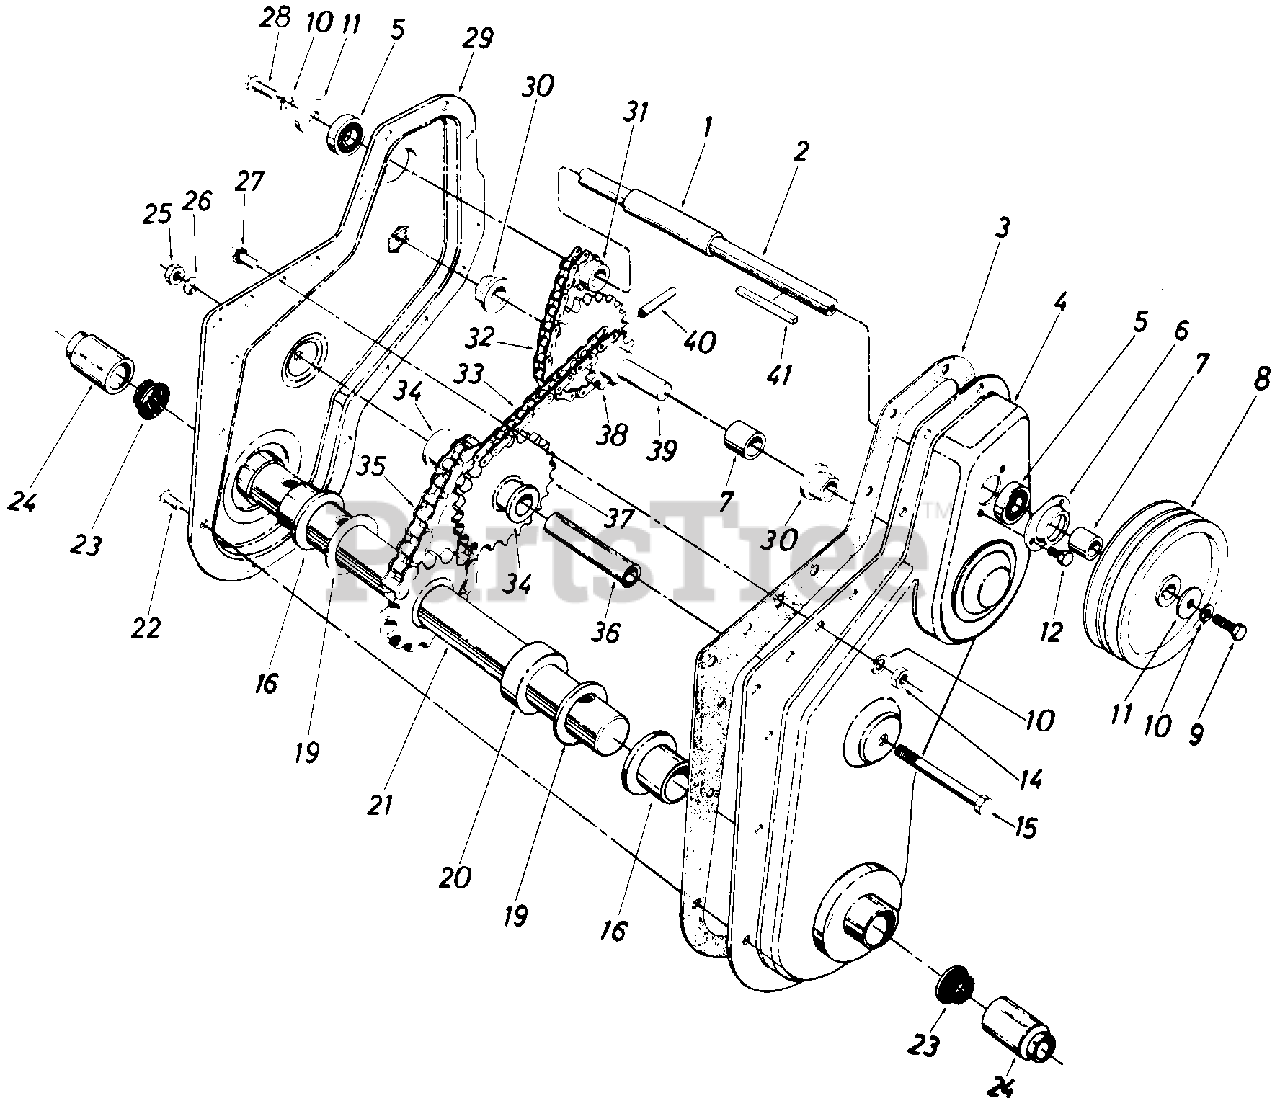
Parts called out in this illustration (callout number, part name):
1	Spacer .657 I.D. x .78 O.D. x 2.19" Lg.
2	Jackshaft
3	Housing Gasket
4	Housing Ass'y. L.H. Half
5	Ball Bearing .625 I.D. x 1.375 O.D.
6	Bearing Housing
7	Spacer .635 I.D. x .88 O.D. x 1.03" Lg.
8	Chain Case Pulley 6.0" Dia.
9	Hex Bolt 5/16-18 x 1.0" Lg.
10	L-Wash. 5/16" I.D.
11	Fl-Wash. .344" I.D. x 1.125" O.D.
12	Hex Wash. Hd. Self-Tap Scr. 1/4-20 x .50" Lg.
14	Hex Nut 5/16-18 Thd.
15	Hex Bolt 3/8-16 x 3.25" Lg.
16	Flange Bearing (Plastic)
19	Flat Thrust Wash.
20	Step Spacer
21	Tine Shaft Ass'y.
22	Hex Wash. Hd. Self-Tap Scr. 1/4 20 x 50" Lg.
23	Seal Ring
24	Dust Cap
25	Hex Nut 3/8-16 Thd.
26	L-Wash. 3/8 I.D.
27	Hex Sems Bolt 5/16-18 x 1.00" Lg.*
28	Hex Bolt 5/16-18 x .62" Lg.
29	Housing Ass'y. R.H. Half
30	Hex Flanged Bearing
31	Sprocket 10 Teeth 1/2" Pitch
32	#41 Chain 1/2" Pitch x 34 Links
33	#420 Chain 1/2" Pitch x 48 Links
34	Flange Bearing .625" I.D.
35	#50 Chain 5/8" Pitch x 28 Links
36	Sprocket Shaft
37	Sprocket Bearing Sleeve Ass 'y.
38	Sprocket Sleeve Ass'y.
39	Sprocket Shaft
40	Spring Pin Spiral 1/4n Dia. x 1.5" Lg.
41	Square Key 3/16 x 3/16 x 1.50" Lg.
